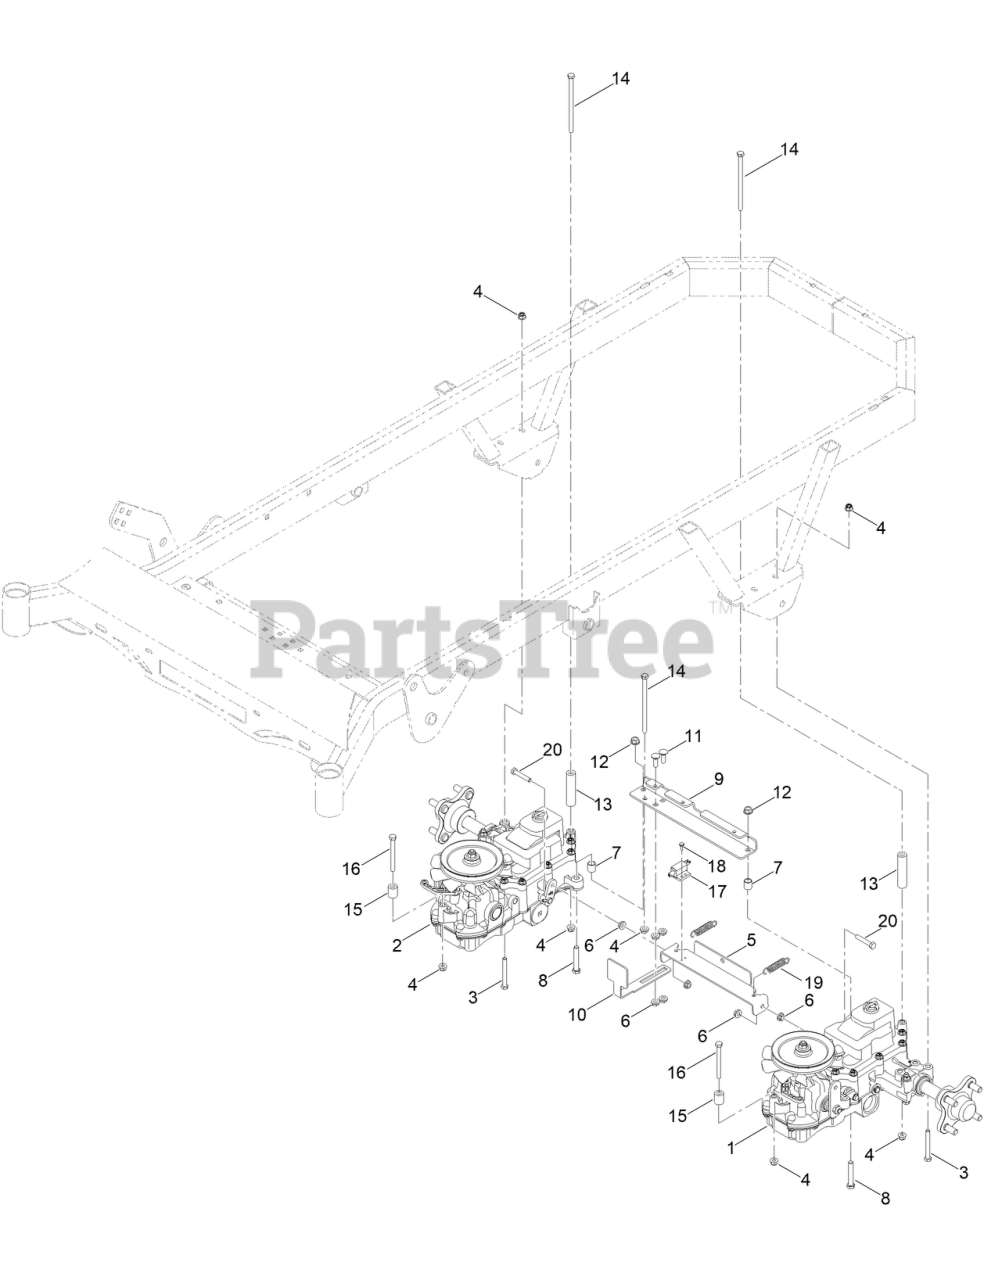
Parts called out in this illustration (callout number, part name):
1	TZ-450 LT SIDE HYDROSTATIC TRANSMISSION
2	TZ-450 RT SIDE HYDROSTATIC TRANSMISSION
3	SCREW-HH
4	NUT-HF, NI
5	MWR TTQ BRAKE CABLE BRKT PAINT
6	NUT-HF
7	11/16INX 1/2IN X 5/8IN SPACER
8	3/8-16 X 2-1/4 HEX FLANGE BOLT GR8 YZ
9	MWR TTQ TRANSMISSION MOUNT BRACE PAINT
10	STAND TRANS BRAKE INTERLOCK BRKT PAINT
11	BOLT-CARR
12	NUT-HHF, WHIZ
13	TTQ HYDROSTATIC TRANSMISSION RR SPACER
14	BOLT-HH
15	PULLEY COVER SPACER/TTQ SHORT SPACER
16	SCREW-HH
17	NO PLUNGER LIMIT SWITCH
18	8-32 X 1/2 IND. HWH SLOT TYPE F TCS ZINC
19	MWR BRAKE PEDAL RELEASE SPRING
20	SCREW-HH
